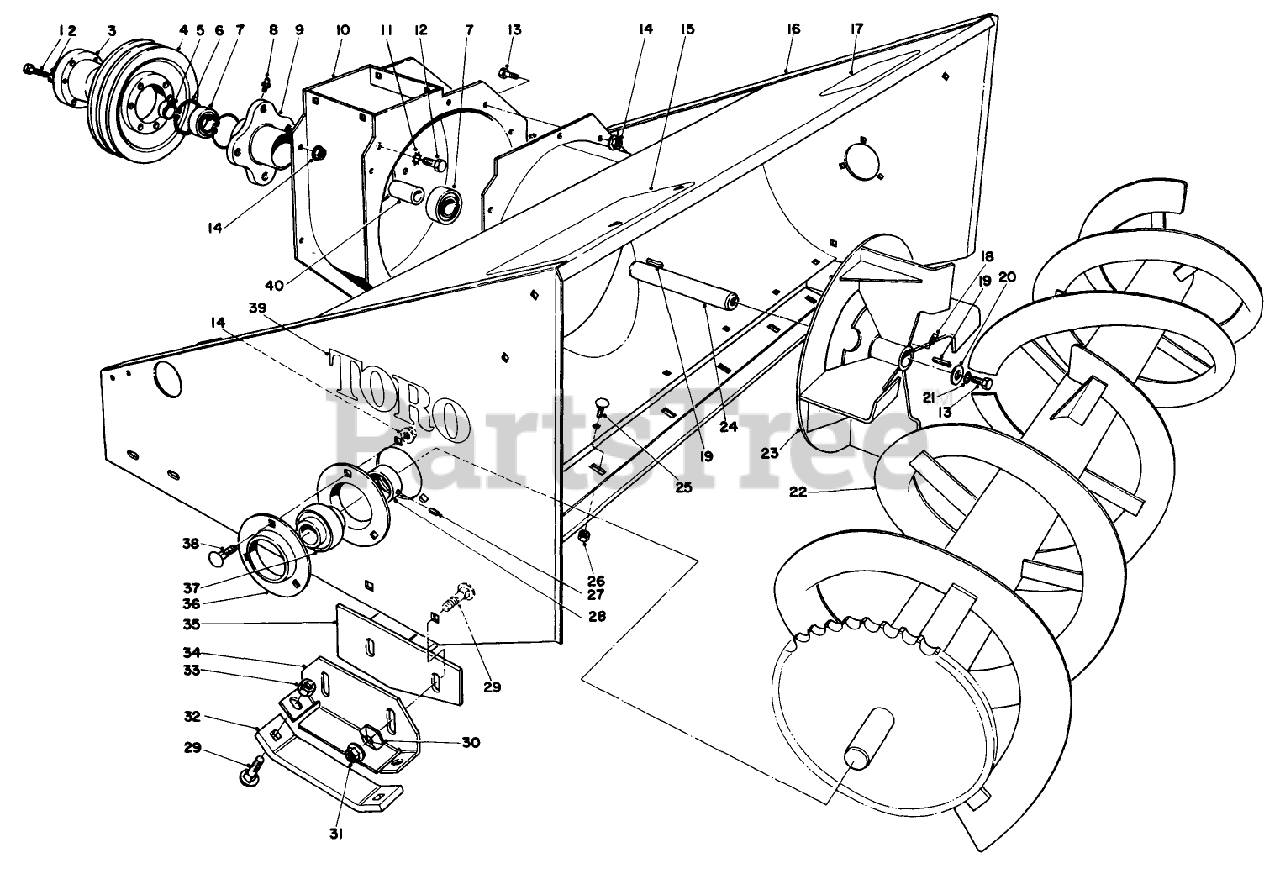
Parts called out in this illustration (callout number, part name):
1	SCREW-HH
2	WASHER-LOCK
3	Hub-"QD" (Incl. Ref. #1 & 2)
4	Pulley-"QD"
5	SPACER
6	RETAINING RING
7	BEARING
8	FITTING-LUBE, 45 DEG
9	SPINDLE HOUSING
10	BLOWER HSG WA
11	WASHER-LOCK, EXT
12	SCREW-HH
13	SCREW-HH
14	NUT-HF
15	Decal-Rear Weight
16	Auger Housing
17	Decal-Warning
18	SCREW-SET
19	Square Key
20	WASHER
21	WASHER-LOCK
22	Auger
23	IMPELLER WA 60096
24	IMPELLER SHAFT
25	SCREW-CARR
26	NUT-LOCK, NI
27	SCREW-SET, HSH
28	COLLAR-LOCK, BEARING
29	BOLT-CARR
30	LOCKWASHER-PYRAMID
31	FLANGE NUT W/LG FLG
32	SKID SHOE R
33	NUT-LOCK, CONE
34	SKID MTG PLT
35	SCRAPER WA
36	FLANGE
37	Bearing (Incl. Ref. #27 & 28)
38	SCREW-CARR
39	DECAL
40	SLEEVE 16107
